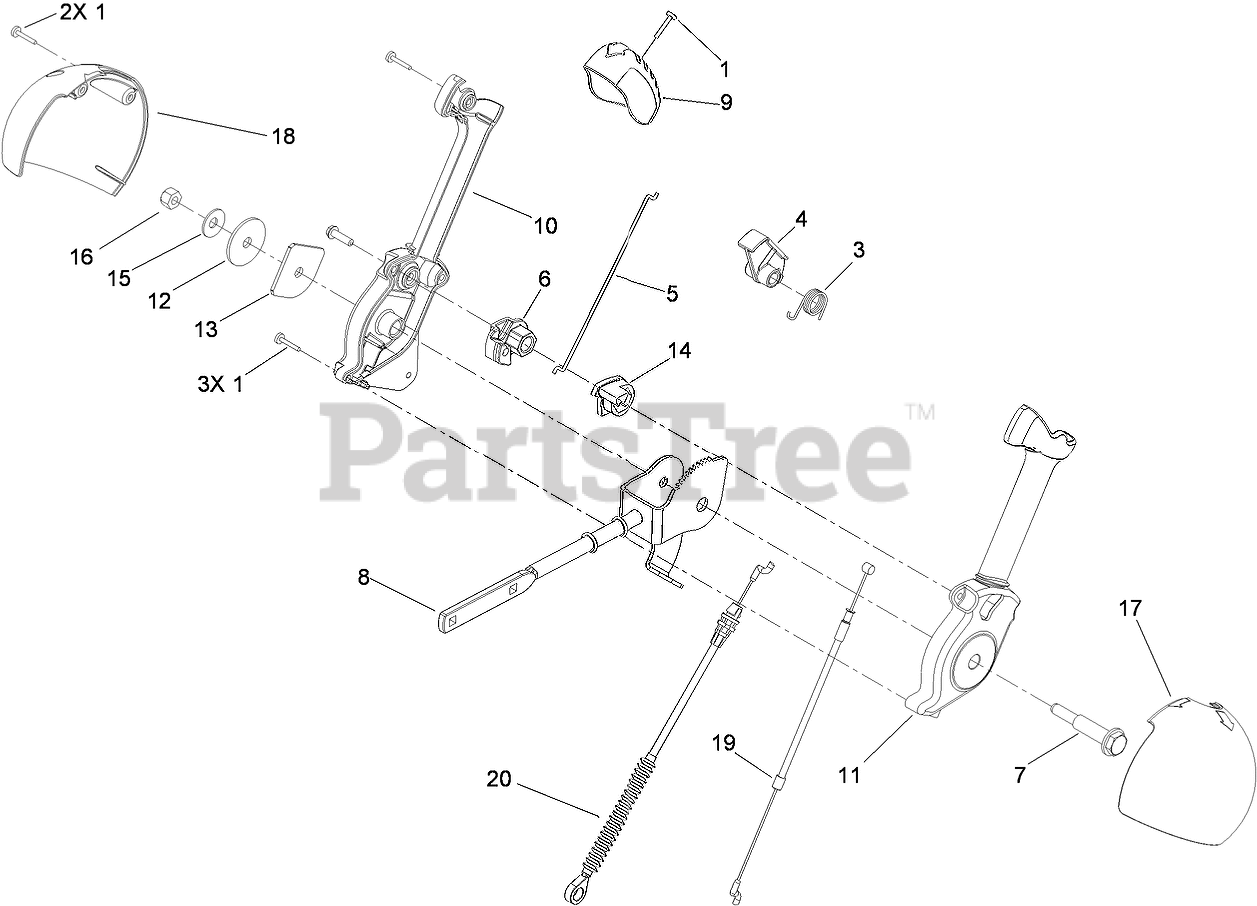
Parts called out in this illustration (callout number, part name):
1	SCREW-PPH
3	SPRING-TORSION
4	TRIGGER-LATCH
5	LINK-LATCH
6	LEVER-CABLE, DEFLECTOR
7	SCREW-SHOULDER
8	ROD-CONTROL, CHUTE
9	CAP-LEVER
10	LEVER-CONTROL, CHUTE (RH)
11	LEVER-CONTROL, CHUTE (LH)
12	WASHER-NYLON
13	PLATE-FRICTION
14	PAWL-LATCH
15	WASHER-BELLEVILLE
16	NUT-LOCK, NI
17	COVER-LEVER, CHUTE (LH)
18	COVER-LEVER, CHUTE (RH)
19	CABLE-RELEASE, CHUTE
20	CABLE-CONTROL, DEFLECTOR
